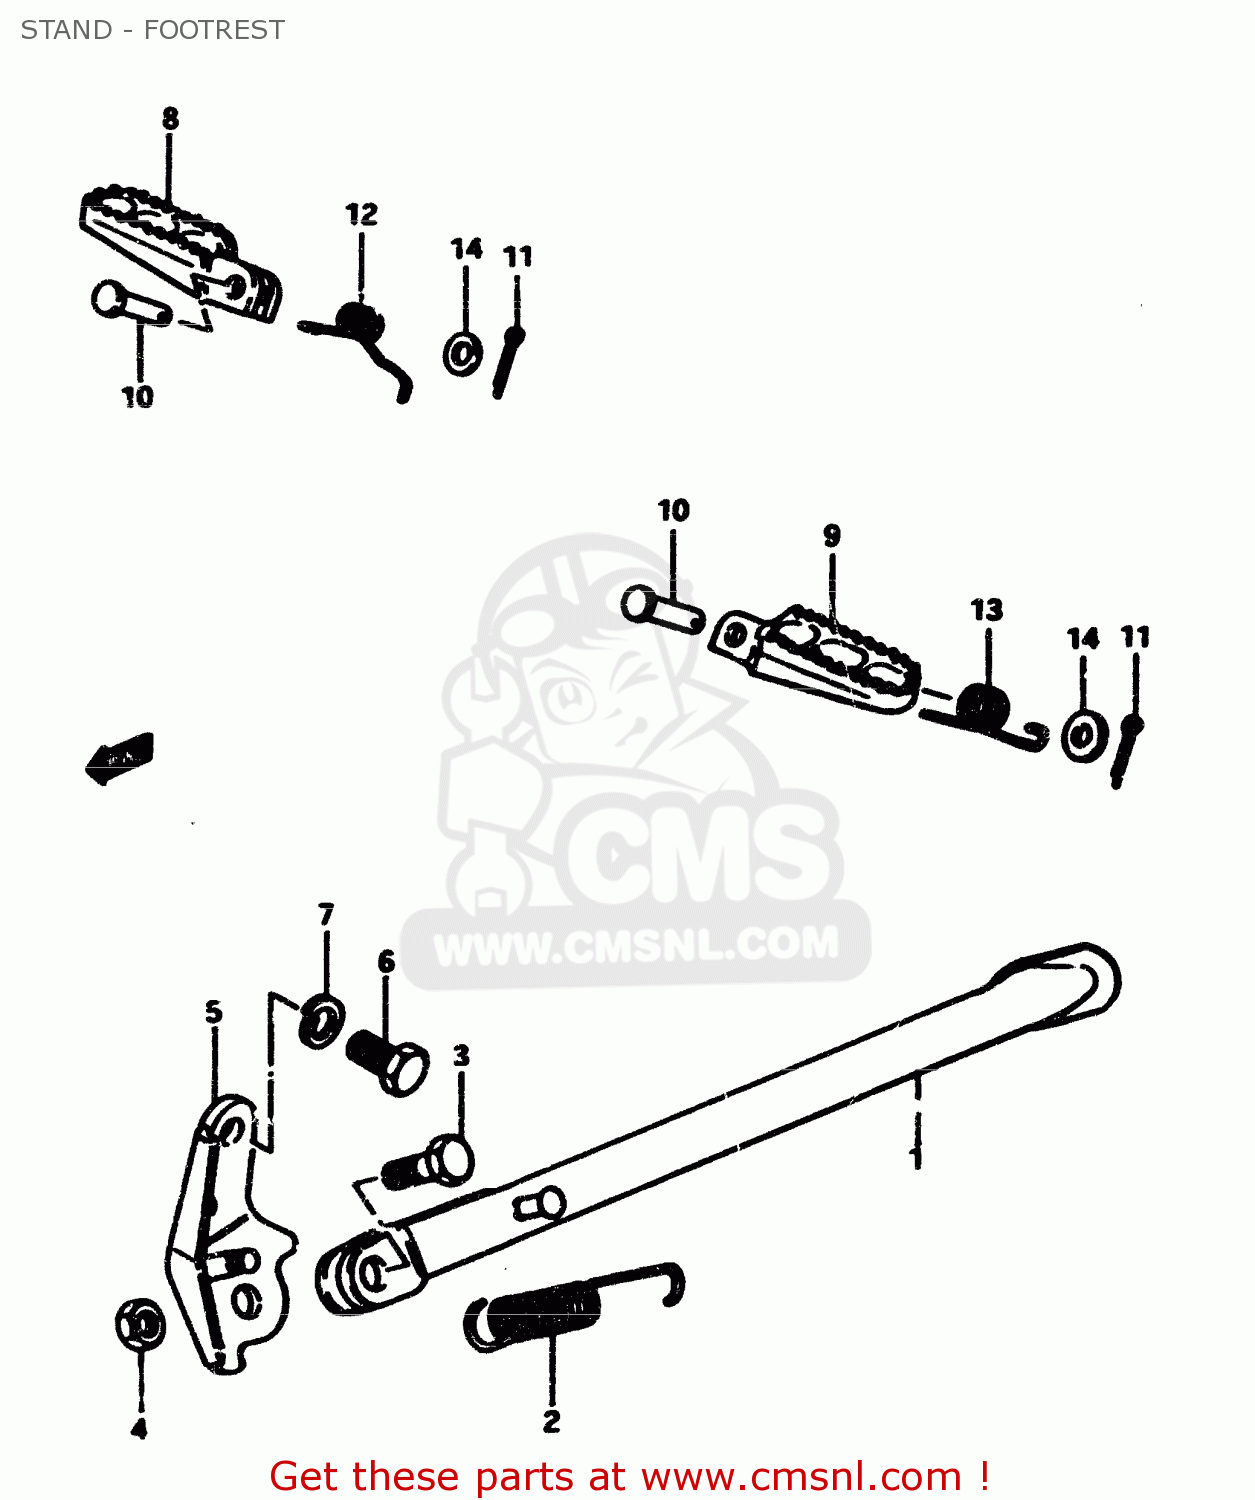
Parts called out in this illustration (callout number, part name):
1	STAND,SIDE
2	SPRING
3	BOLT(10X30)
4	NUT
5	BRACKET,SIDE STAND
6	BOLT(10X19)
7	LOCK WASHER
8	FOOTREST
9	FOOTREST
10	PIN
11	PIN 20X20
12	SPRING
13	SPRING,FOOTREST,LEFT
14	WASHER
